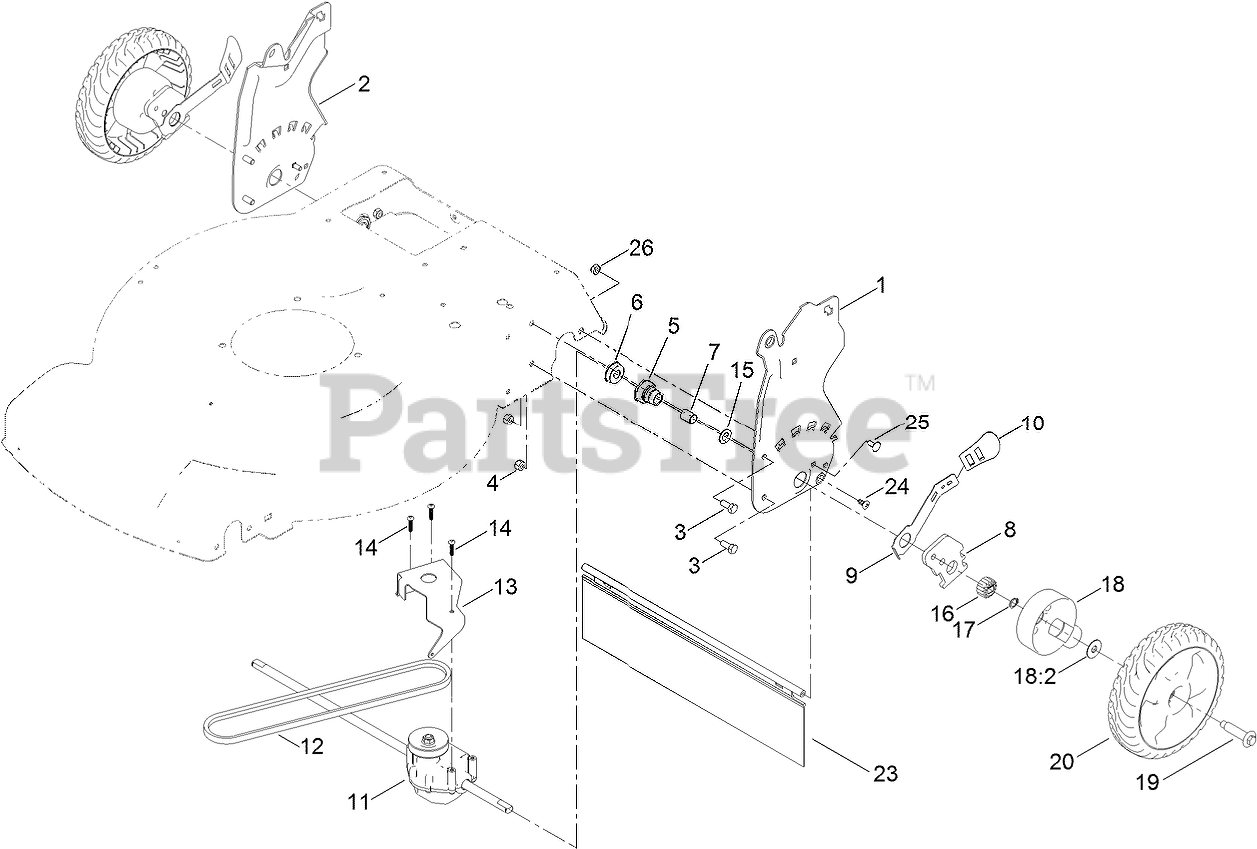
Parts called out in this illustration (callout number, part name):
1	PLATE-HOC, LH
2	PLATE-HOC, RH
3	SCREW-HH
4	NUT-HEX
5	RETAINER-BUSHING, HOC
6	BEARING-BALL
7	BUSHING-SLEEVE
8	ARM-PIVOT, REAR
9	ARM-SPRING
10	KNOB-HOC
11	TRANSMISSION ASM
12	BELT-V
13	BRACKET-TRANSMISSION
14	SCREW-PLASTITE
15	WASHER-THRUST
16	GEAR-PINION, 15T
17	RING-RETAINING
18	GEAR COVER ASM
18:2	WASHER-STEPPED
19	BOLT-SHOULDER
20	WHEEL GEAR ASM, 8IN
23	SHIELD-TRAILING
24	SCREW-THD
25	BOLT-CARR
26	NUT-LOCK
